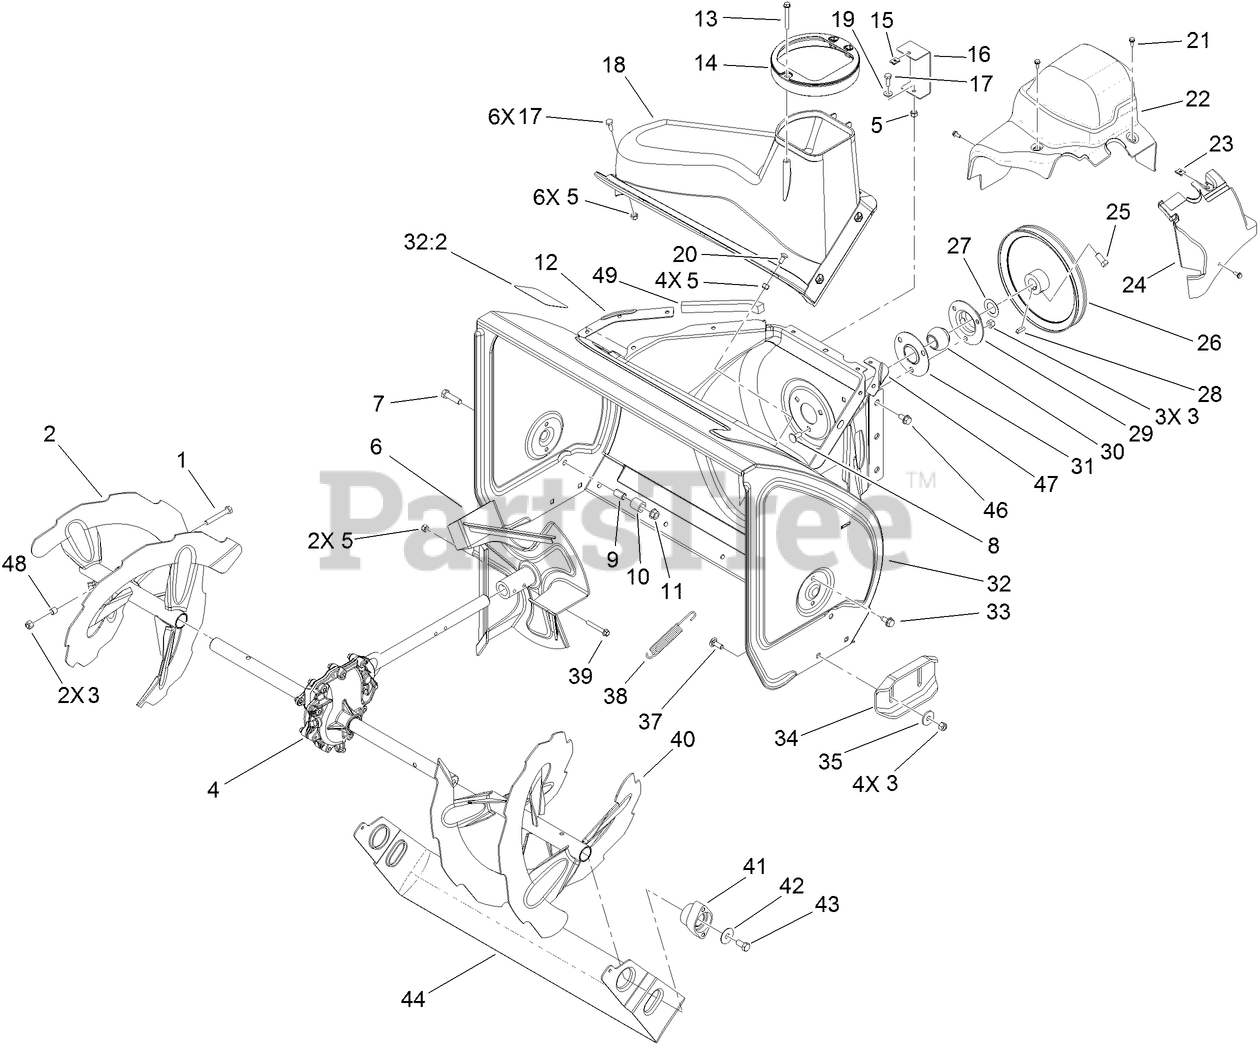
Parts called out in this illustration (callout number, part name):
1	SCREW-HH
2	RH AUGER ASM
3	NUT-LOCK, NI
5	NUT-LOCK, NI
6	IMPELLER ASM
7	SCREW-HH
8	SCREW-CARR
9	SPACER-SCRAPER, STOP
10	CUSHION-SCRAPER, STOP
11	NUT-HF
12	SEAL-FLANGE, COVER
13	SCREW-PLASTITE
14	GUIDE-CHUTE
15	NUT-SPEED
16	BRACKET-COVER, CLIP NUT
17	SCREW-HH
19	WASHER-FLAT
20	BOLT-CARR
21	SCREW-HWH
22	COVER-BELT
23	NUT-SPEED
24	COVER-EXTENSION, BELT
25	SCREW-SET, SQH
27	WASHER-THRUST
28	KEY-WOODRUFF
29	FLANGE-CUP, BEARING
30	BEARING-BALL
31	FLANGE-CUP, BEARING
32	HOUSING-AUGER, 28 INCH
32:2	DECAL-DANGER
33	SCREW-HWHTF
35	WASHER
37	SCREW-CARR
38	SPRING-SCRAPER
39	SCREW-HH
40	LH AUGER ASM
41	BEARING-AUGER
42	WASHER
43	SCREW-HH
44	SCRAPER-PIVOTING, 28 INCH
46	SCREW-HWHTF
48	SPACER
49	SEAL-HOUSING
